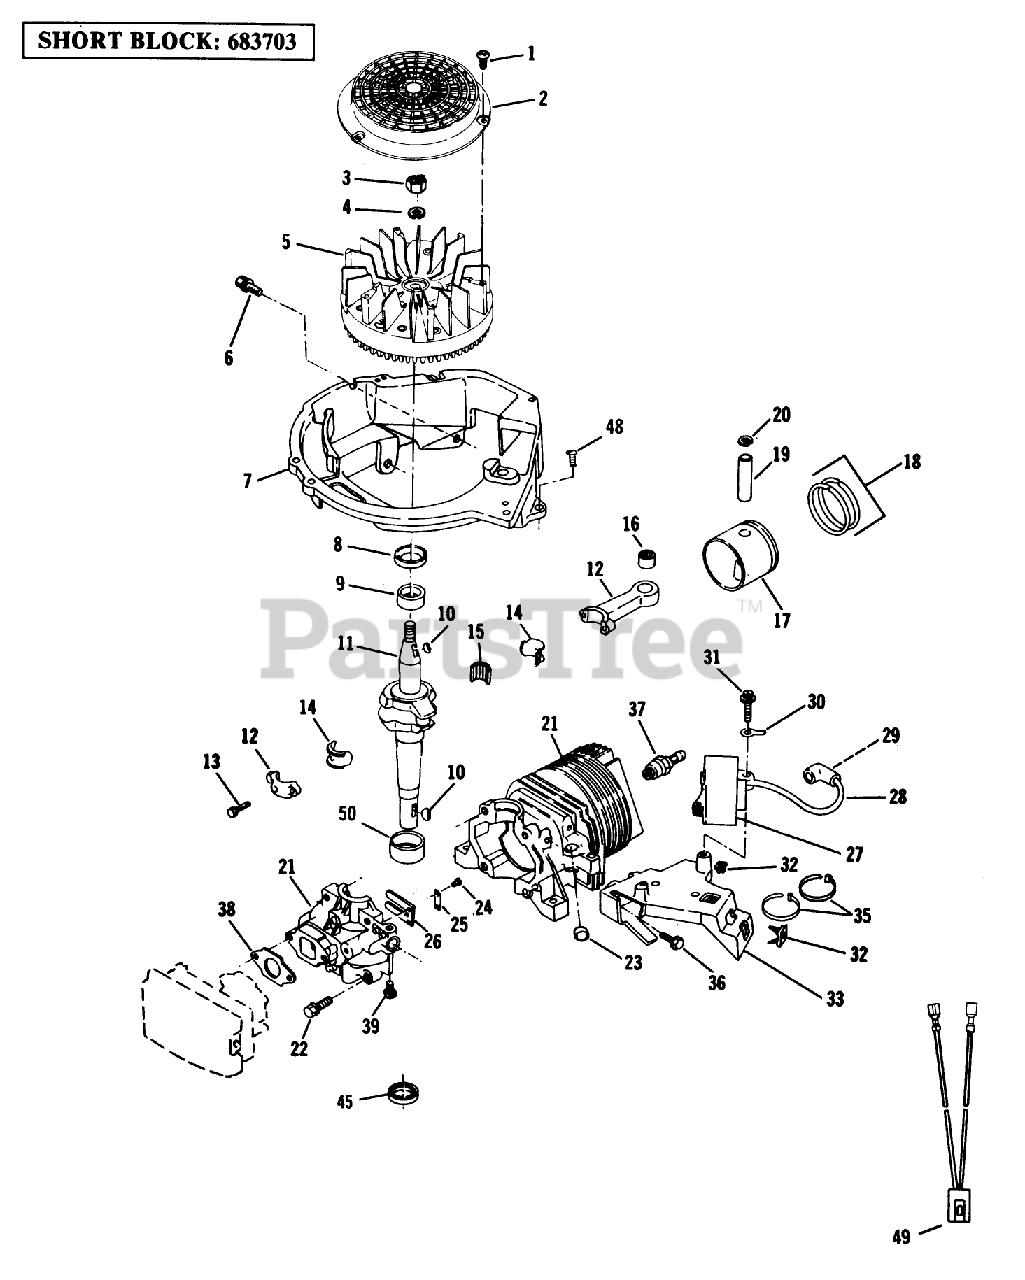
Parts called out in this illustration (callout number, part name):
1	SCREW F
2	SCREEN F'WHEEL S
3	NUT
6	SCREW-SEMS
7	BASE SHROUD PL
9	BEARING V
10	KEY
13	SCREW-HSH
14	LINER ASM
16	BEARING AY F
20	RING-RETAINING
22	SCREW S
23	PLUG-CORE VF
25	PLATE-BACKUP, REED
28	HT LEAD&COVER XEV
30	TERMINAL S
32	NUT-CLIP
33	BRACKET S
38	GASKET CARB S
45	SEAL-OIL
48	SCREW F
50	BEARING V
